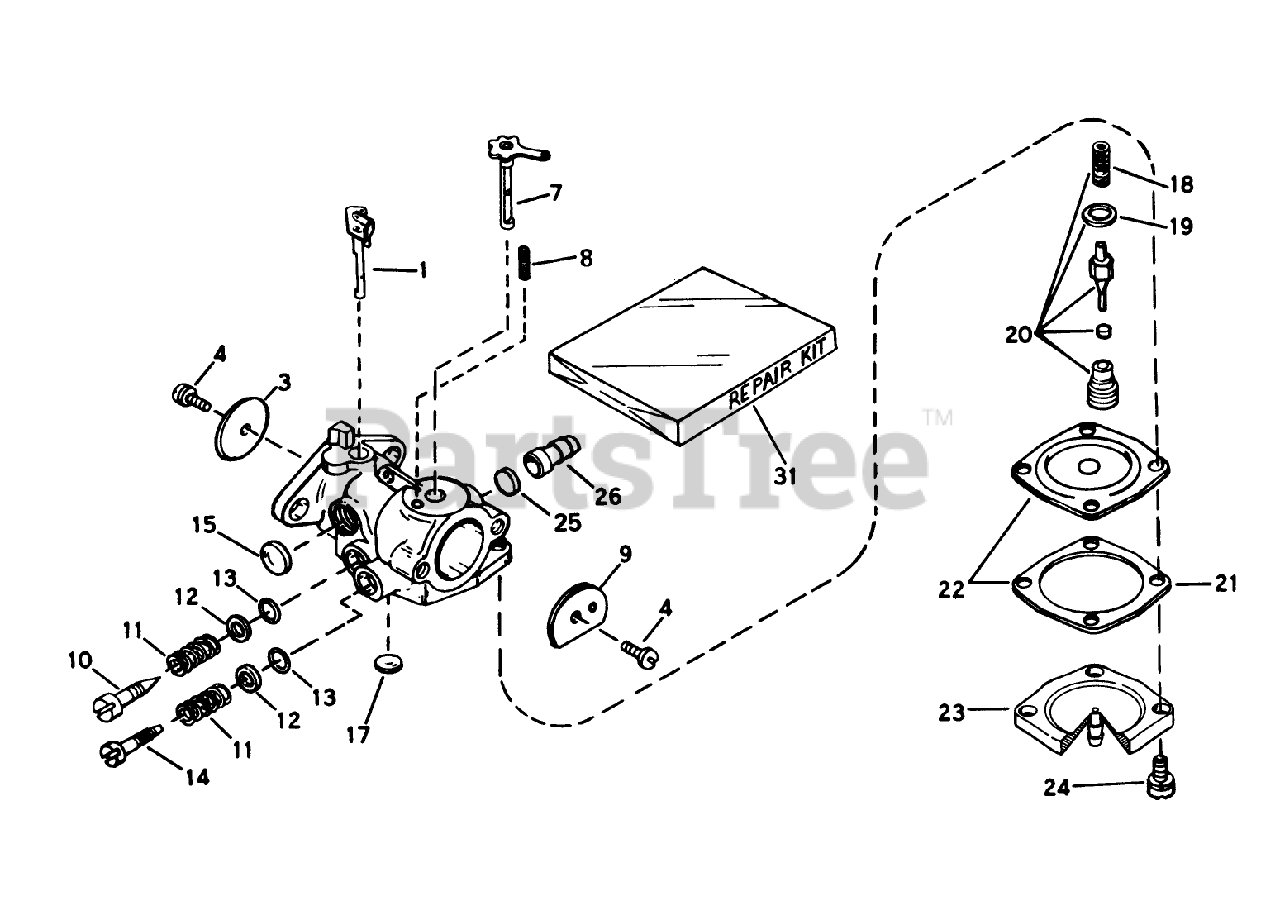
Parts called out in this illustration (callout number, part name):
1	Shaft/Lever-Throttle
3	Shutter-Throttle
4	Screw-Shutter
7	Shaft Lever Assembly
8	Spring-Positioning, Choke
10	Screw-Idle Adjustment
11	Spring
12	Washer
13	ORing
14	Screw Main Adjustment
15	Plug-Welch, Idle Mixture Well
17	Plug-Welch, Idle Mixture Well
18	Spring-Valve
19	Gasket-Valve Seat
20	Inlet Needle, Seat, Spring Gasket Assy. (lncl. #1819)
21	Gasket-Diaphragm
22	Diaphragm Ass. (Incl. No. 21)
23	Cover-Diaphragm
24	Screw
26	Fitting-Fuel
31	Kit-Repair
